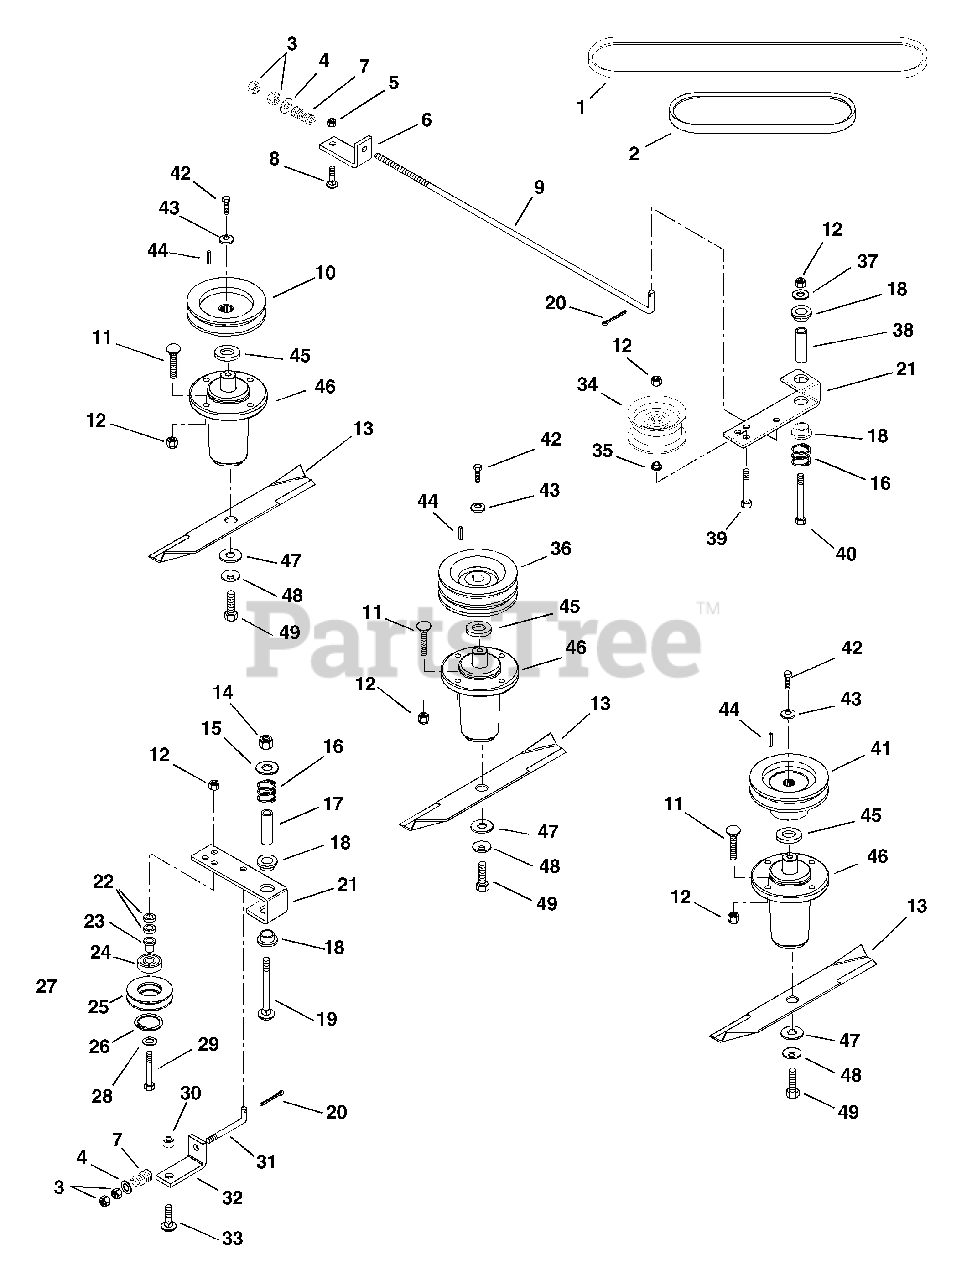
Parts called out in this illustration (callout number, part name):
1	V-Belt, A-Section 42.15 x .516/.031
2	V-Belt, A-Section 18.05 x .495
3	Nut-Hex .375-16
4	Washer-Flat-Steel .406 x .812 x .065
5	Nut-Locking-Nylon .31-18
6	Bracket, Belt Tensioner
7	Spring-Compression .125 x .781 x 1.00 338 lbs/in
8	Bolt, Round Head Square Neck .31-18 x 1.0
9	Rod, Idler
10	Sheave
11	Bolt, Round Head Square Neck .31-16 x 1.375
12	Nut-Locking-Nylon .375-16
13	Blade, 50" Mower
14	Nut-Locking .50-13 Hex Type Needle
15	Washer-Flat-Steel .531 x 1.250 x .100
16	Spring-Compression .085 x .80 x 1.00
17	Spacer, .560 x .750 x 2.437 Steel
18	Bushing-Flange .762 x 1.0 x .580 x 1.48 Nylon
19	Bolt, Round Head Square Neck .50-13 x 3.50
20	Pin, Cotter .09 x .75
21	Arm, Idler Pivot
22	Bushing .406 x .750 .188
23	Bushing-Flange .786 x 1.0 x .79
24	Bearing-Ball 1.85 x .787 x .55
25	Sheave, Idler
26	Ring-Retaining-Internal 2.054 x .062
27	Assembly, Idler Sheave
28	Washer-Flat-Steel .375 x 1.125 x .065
29	Bolt-Hex .38-16 x 2.00 Grade 5
30	Nut-Locking-Nylon .50-13 Grade 5
31	Rod, Idler
32	Bracket, Belt Tensioner
33	Bolt, Round Head Square Neck .31-18 x 1.50
34	Idler, Flat
35	Bushing-Flange .406 x .88 x .270 x .140
37	Washer-Flat-Steel .438 x 1.000 x .083
38	Bushing, Steel .437 x .750 x 2.44
39	Bolt-Hex .28-16 x 2.25 Grade 5
40	Bolt-Hex .38-16 x 3.25 Grade 5
42	Bolt-Hex .38-16 x 1.00 Grade 8
43	Washer-Cupped Serrated .375
44	Key-Straight .25 x 1.00 x .25
45	Slinger-Dust
46	Assembly-Spindle
47	Washer-Flat .640 x 1.81.x..250
48	Washer-Bellville .63 x 1.625 x .14
49	Bolt-Blade
